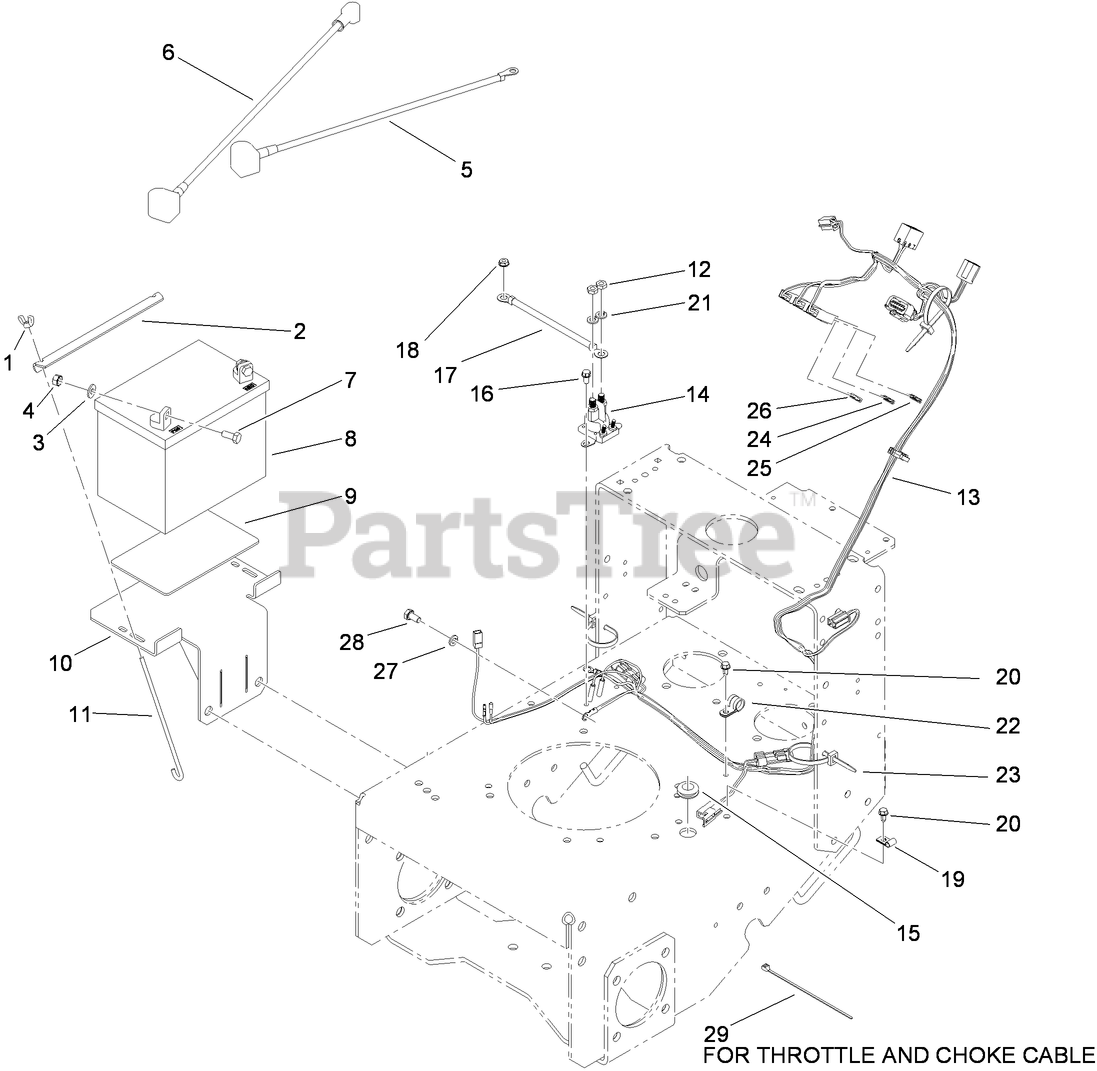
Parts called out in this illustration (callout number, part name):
1	WINGNUT
2	ANGLE-BATTERY
3	WASHER-FLAT
4	NUT-KEPS
5	CABLE-BATTERY, BLACK
6	CABLE-BATTERY, RED
7	SCREW-HH
8	BATTERY-DRY
9	PAD-SKID, ANTI
10	TRAY-BATTERY
11	BOLT-HOLDDOWN
12	NUT-JAM
13	HARNESS-WIRE, ES TWIN LEVER
14	SWITCH-SOLENOID
15	GROMMET
16	SCREW-HWH
17	CABLE-BATTERY, POS
18	NUT-KEPS
19	CLIP-CLOSED, INSULATED
20	SCREW
21	WASHER-LOCK
22	CLAMP-R
23	TIE-CABLE
24	FUSE-BLADE, 25 AMP
25	FUSE-BLADE, 30 AMP
26	FUSE-BLADE, 10 AMP
27	WASHER-LOCK
28	SCREW-HH
29	TIE-CABLE
